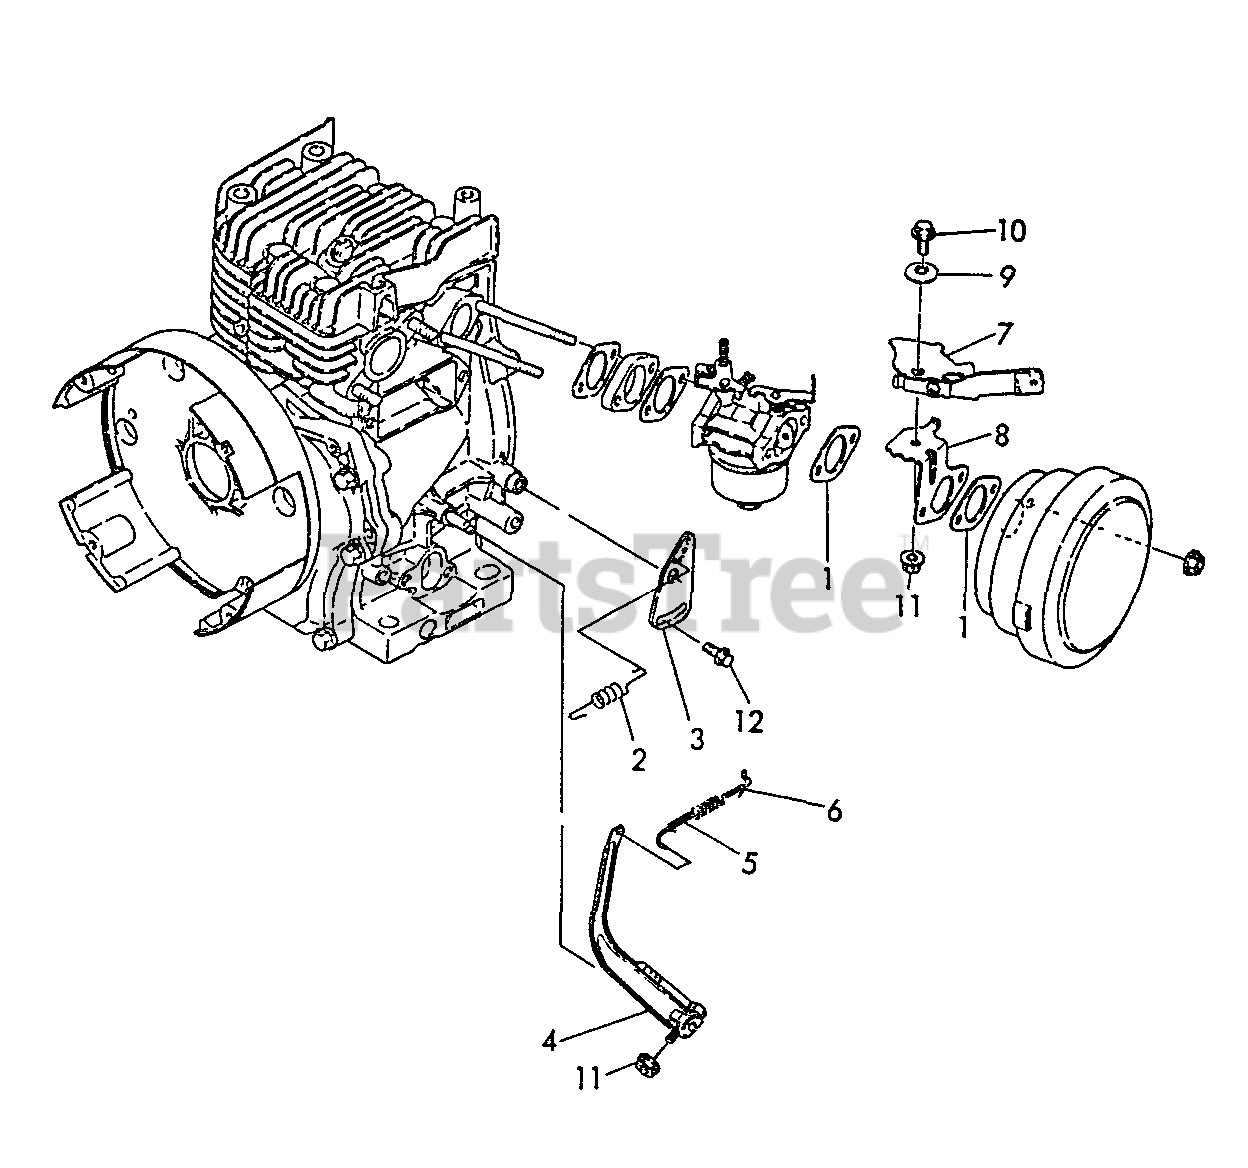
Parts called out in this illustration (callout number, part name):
1	GASKET, INTAKE
2	SPRING, REGULATOR
3	HANDLE, REGULATOR
4	LEVER, GOVERNOR
5	LINK, THROTTLE
6	SPRING
7	LEVEL ASSY
8	BRACKET
9	COLLAR
10	BOLT - 6X12 -- PLATED
11	NUT - 6 -- FLANGE
12	BOLT - 6X8 -- PLATED
